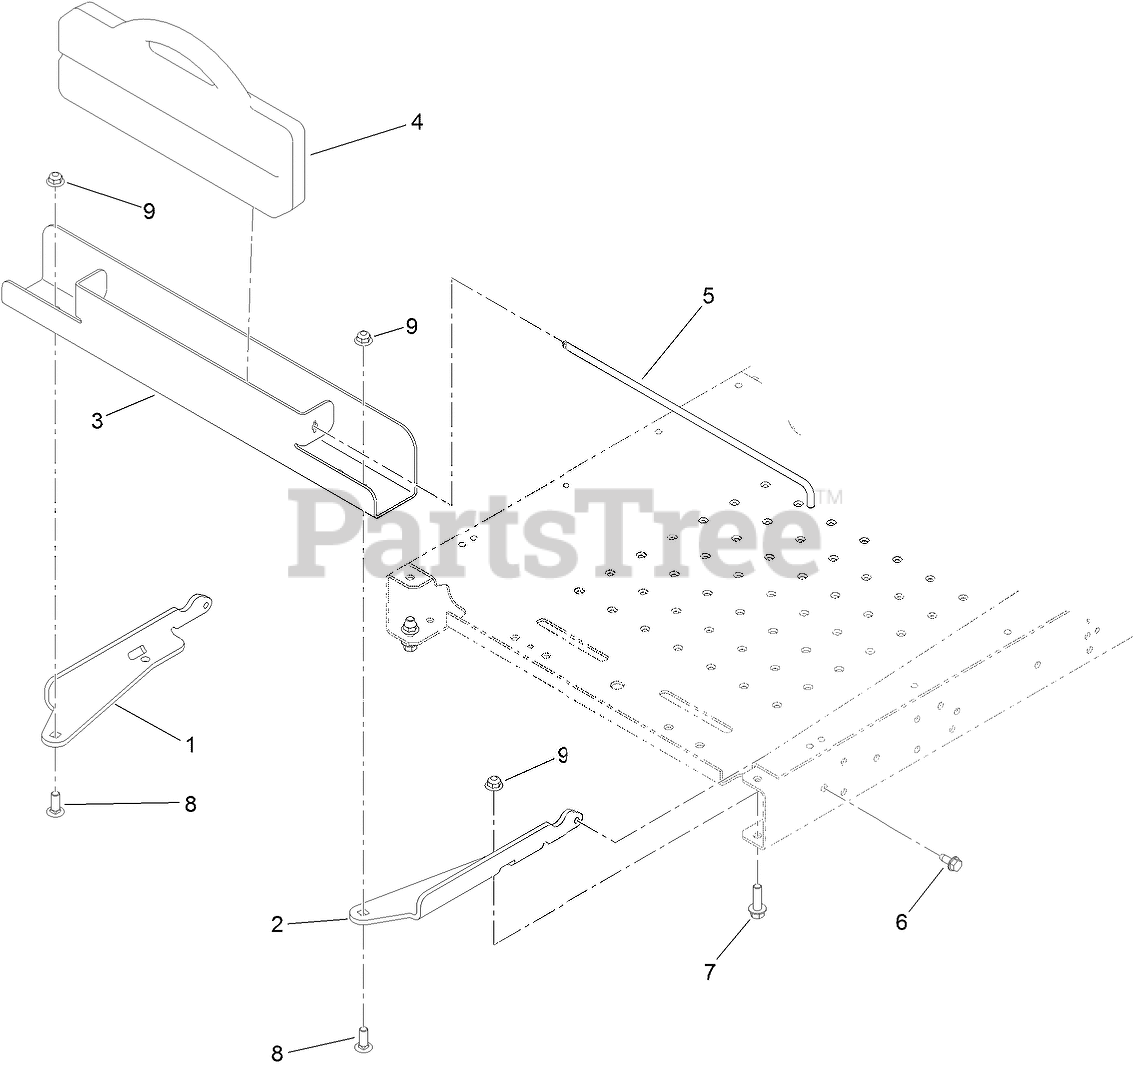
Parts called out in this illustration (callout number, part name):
1	BRACKET-WEIGHT, RH
2	BRACKET-WEIGHT, LH
3	CHANNEL-WEIGHT, BAGGER
4	WEIGHT-35 POUND
5	ROD, WEIGHT LOCK
6	SCREW-HWHTF
7	SCREW-HHF
8	BOLT-CARR
9	NUT-HF, NI
